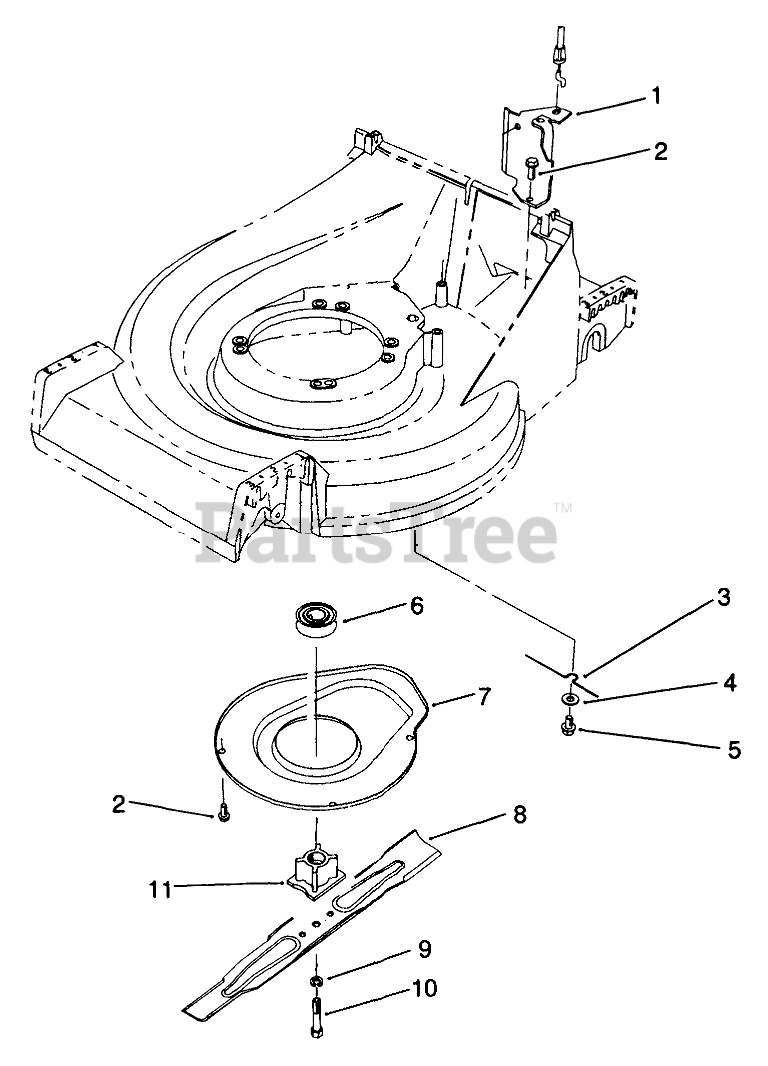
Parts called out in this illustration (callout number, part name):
1	Bracket-Cable Support
2	SCREW-HWHTF
3	RETAINER-BELT
4	WASHER-FLAT
5	SCREW-HHFTF
6	PULLEY-DRIVE, ZONE START
7	Cover
8	Key
9	WASHER-LOCK
10	SCREW-BLADE
11	BLADE RETAINER
